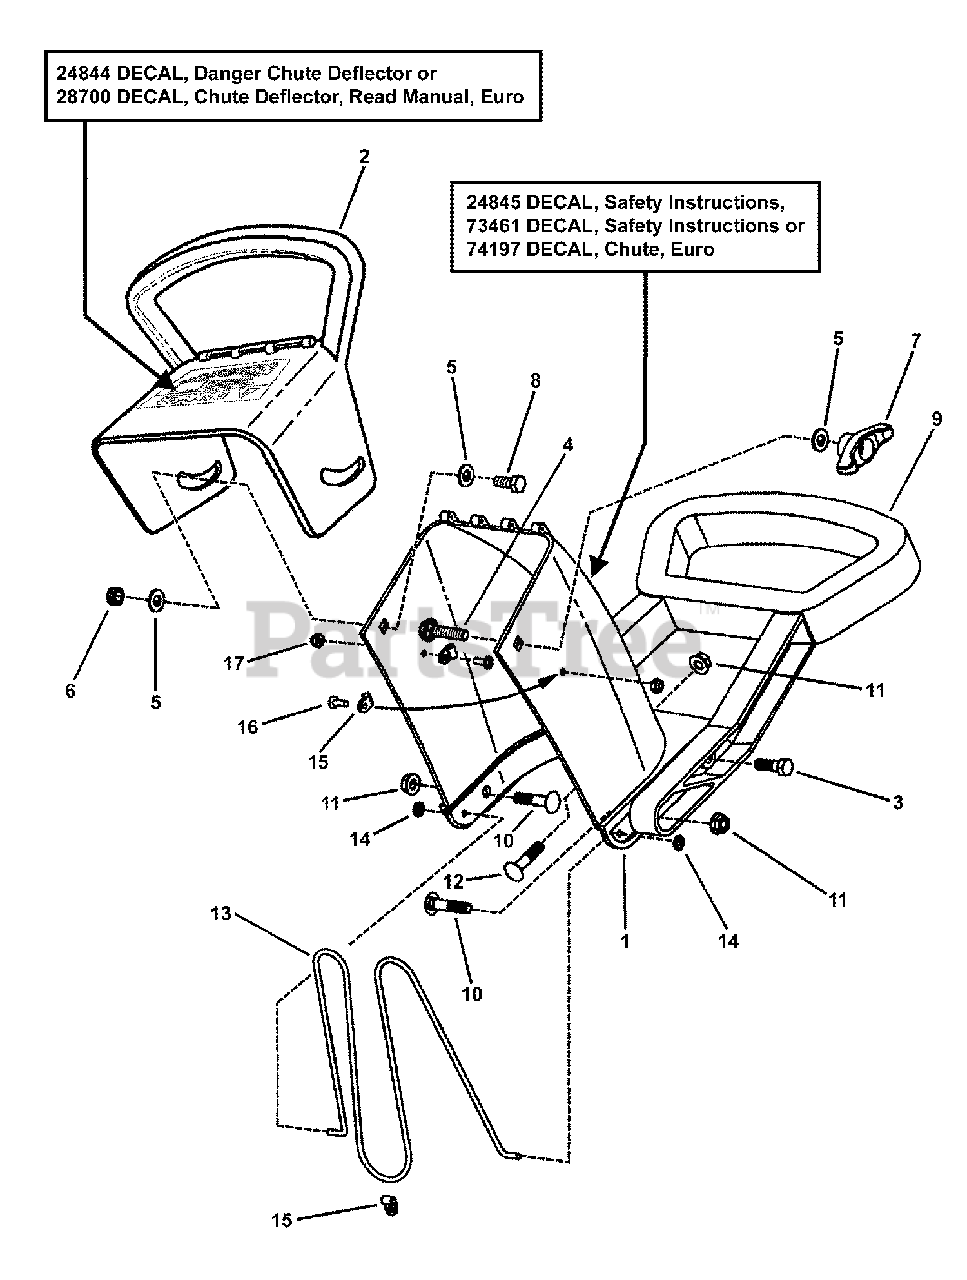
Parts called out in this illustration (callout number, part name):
1	CHUTE, Discharge w/inserts
1	CHUTE, Discharge w/inserts (incl. decal # 24845)
2	DEFLECTOR, Chute (incl. decal # 24106)
2	DEFLECTOR, Chute (incl. decal # 24844)
3	SCREW, 5/16-18 x 3/4" Hex Head Cap, GR 2
4	BOLT, 5/16-18 x 1" Short Neck Carriage, GR 5
5	WASHER, 5/16" Flat
6	NUT, 5/16-24 Hex Center Lock, GR B
7	KNOB, 5/16-18 Wing (Black)
8	SCREW, 5/16-24 x 3/4" Hex Head Cap, GR 5
9	HANDLE, Chute Control
10	BOLT, 5/16-18 x 1-1/2" Square Neck Carriage, GR 5
11	NUT, 5/16-18 Hex Flange Lock, GR 5
12	BOLT, 5/16-18 x 3/4" Short Neck Carriage, GR 5
13	WIRE, Safety
14	FASTENER, Push On, .156 Internal Diameter
15	CLIP, Guard
16	SCREW, #8-32 x 1/2" Pan Head Cross Recess
17	NUT, #8-32 Hex (w/free spinning external lock washer)
